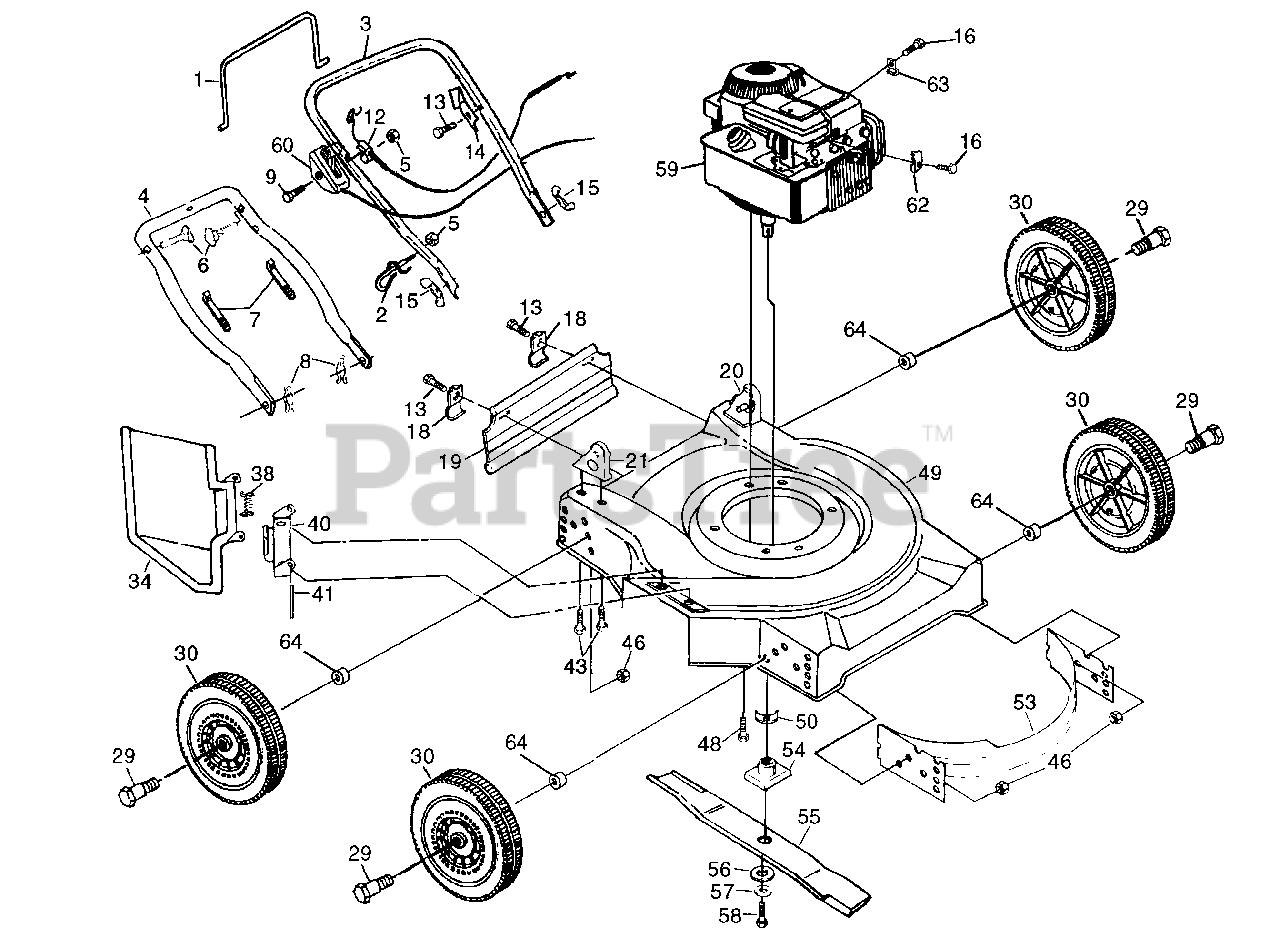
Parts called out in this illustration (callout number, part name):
1	Control Bar
2	Rope Guide
3	Upper Handle
4	Lower Handle
5	Locknut 1/4-20
6	Handle Bolt 5/16-18
7	Wire Tie
8	Hairpin Cotter
9	Machine Screw 1/4-20 x 2.12
12	Engine Zone Control Cable
13	Hex Washer Head Screw #10-24 x 1/2
14	Up-Stop Bracket
16	Screw #10 x 5/8
18	Skirt Bracket
19	Rear Skirt
20	Handle Bracket Assembly (Left)
21	Handle Bracket Assembly (Right)
29	Shoulder Bolt
30	Wheel & Tire Assembly
34	Discharge Guard
38	Spring
40	Housing Bracket
43	Thread Cutting Screw 5/16-18 x 3/4
46	Locknut 3/8-16
48	Hex Head Thread Rolling Screw 3/8-16 x 1-1/8
49	Housing Assembly
53	Baffle
54	Blade Adapter
56	Hardened Washer
57	Helical Lockwasher 3/8
58	Hex Head Screw 3/8-24 x 1-3/8 Gr. 8
60	Throttle Control Std.
62	Cable Clamp, B & S
63	Engine Clip
